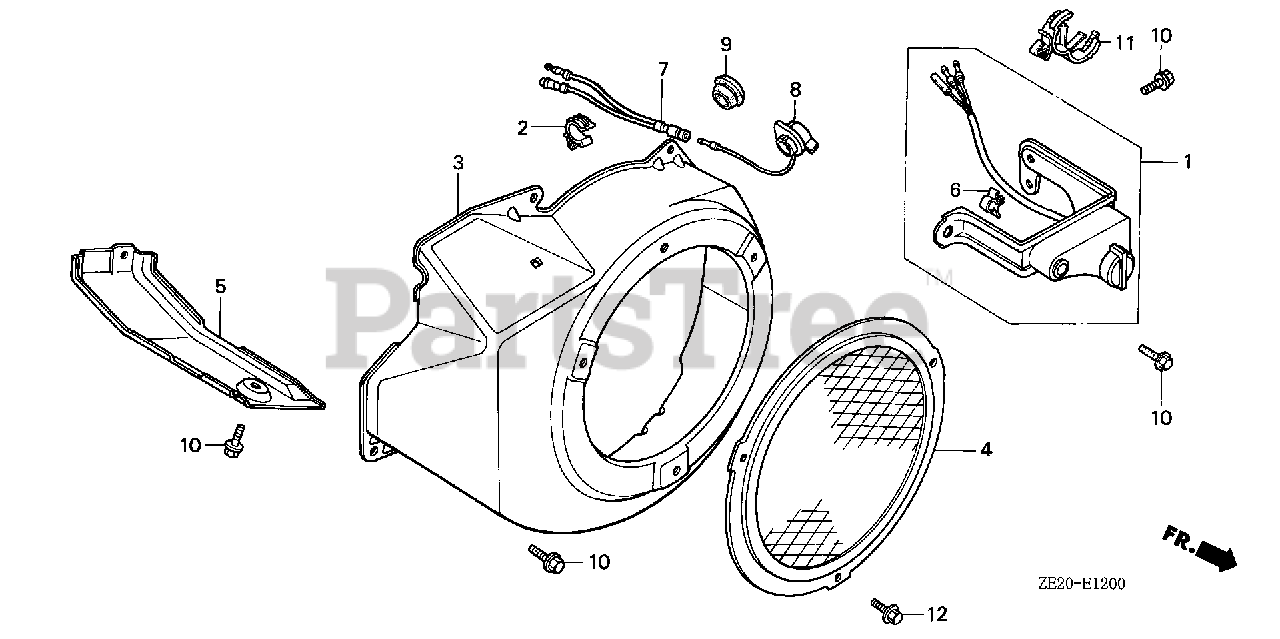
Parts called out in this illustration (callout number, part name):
1	ALERT UNIT, OIL SWITCH ENGINE STOP
2	CLIP, TUBE
3	COVER, FAN *R280* (POWER RED)
5	SHROUD
5	SHROUD (NOT AVAILABLE)
6	CLIP, IGNITION WIRE (8MM)
9	GROMMET, DRAIN HOLE
10	BOLT, FLANGE (6X12) (CT200)
11	CLIP, HARNESS
